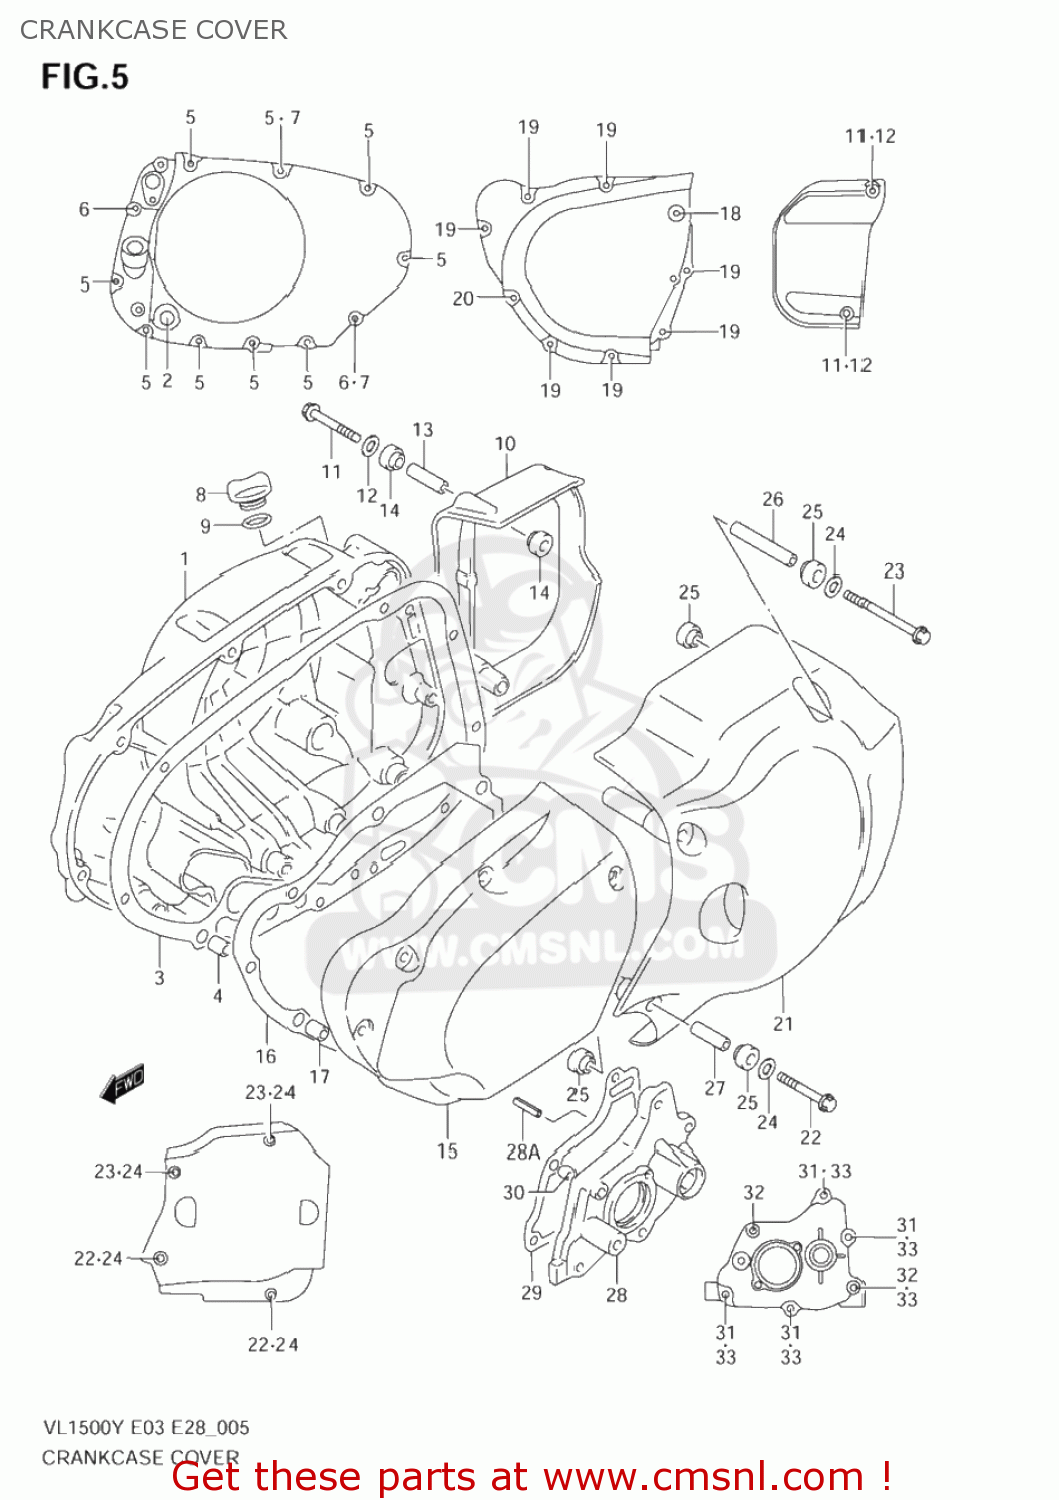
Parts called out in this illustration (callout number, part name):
1	COVER,CLUTCH
2	LENS,OIL LEVEL CHECK
3	GASKET,CLUTCH COVER (NAS)
4	PIN
5	BOLT
6	BOLT
7	GASKET(5.8X11X1.2) (NAS)
8	PLUG
9	O RING(D:3.1,ID:16.8)
10	COVER,CLUTCH RR
11	BOLT
12	WASHER(6.5X14X1.6)
13	SPACER(6.5X9X31.5)
14	WASHER(8.7X16X5)
15	COVER,GENERATOR
16	GASKET,GENERATOR COVER (NAS)
17	PIN(8.4X11X20)
18	BOLT
19	BOLT
20	BOLT
21	COVER,SECONDARY DRIVE UNIT
22	BOLT
23	BOLT
24	WASHER(6.5X14X1.6)
25	WASHER(8.7X16X5)
26	SPACER(6.1X9X55.9)
27	SPACER(6.5X9X26)
28	COVER,GEAR SHIFT
28A	PIN,SPRING(3.5X16)
29	GASKET,GEAR SHIFT COVER (NAS)
30	PIN
31	SCREW
32	BOLT
33	GASKET(5.8X11X1.2) (NAS)
